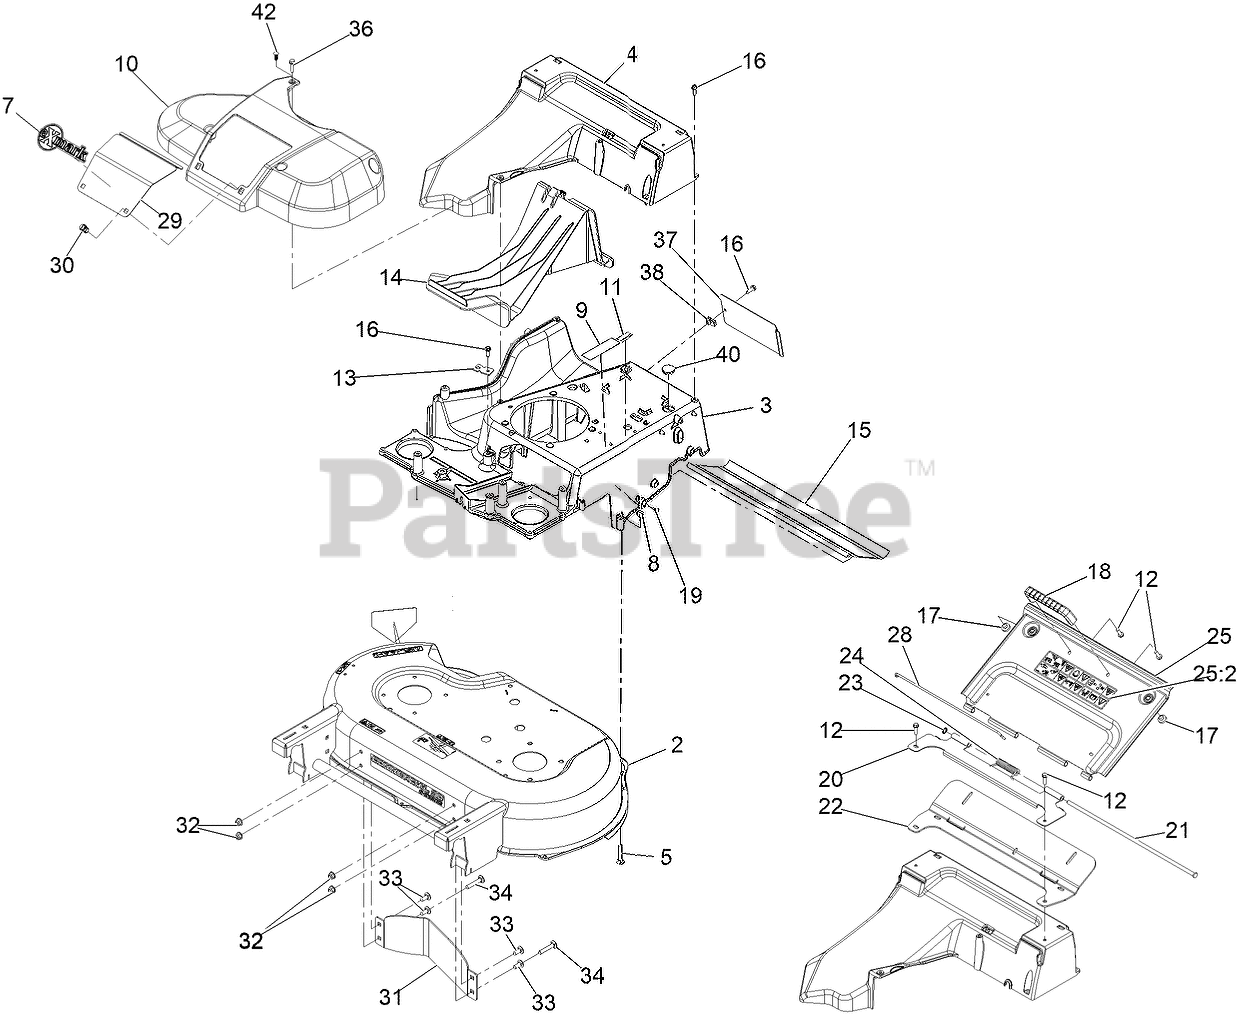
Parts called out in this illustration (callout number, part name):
2	DECK-30, X-SERIES W/DECALS
3	FRAME
5	BOLT-CAR
7	DECAL-EXMARK LOGO
8	NUT-LOCK, NI
10	COVER-BELT
11	Decal-Patent Ttco.Com
12	SCREW-HWH
13	BRACKET-CABLE, TRACTION
14	PLUG-MULCH
15	SHIELD-TRAILING
16	SCREW-HWHTF
18	HANDLE-DOOR
19	SCREW-PTH
20	BRACKET-HINGE
21	PIN-HINGE
22	SEAL-DOOR
23	RING-RETAINING
24	SPRING-TORSION, COVER
25	REAR DOOR ASM
25:2	DECAL-WARNING
28	CLIP-SEAL
29	DOOR-ACCESS
30	FASTENER
31	BAFFLE-CONTROL
32	NUT-HF, NI
33	SCREW-HSBH
36	SCREW-HWHTF
37	Cover-Frame
40	PLUG-BUTTON
